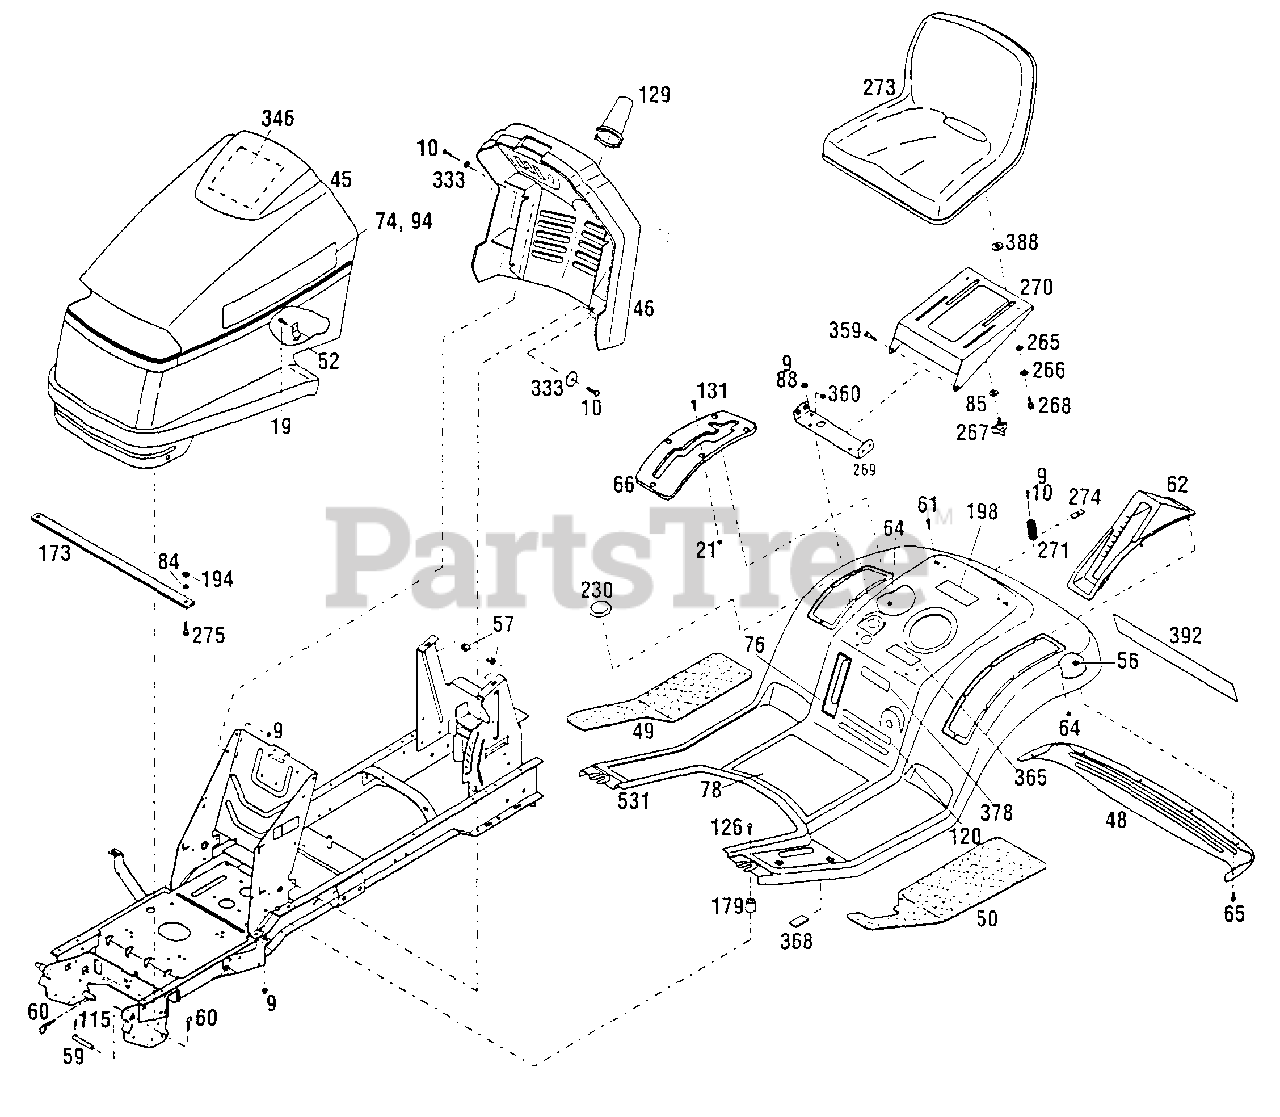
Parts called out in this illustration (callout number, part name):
9	Flange Nut, 5/16-18
10	Hex Head Capscrew, 5/16-18 x 3/4
19	Self Threading Screw, #10
21	Nylon Locknut 1/4-20
46	Console
48	Rear Fender Trim
49	Right Foot Pad 1
50	Left Foot Pad
52	Latch
56	Flange Nut, 1/4-20
57	Self-Retaining Nut, 5/16-18
59	Hood Pivot Pin 1
60	Cotter Spring, 1/8
61	Screw, 5/16-18 x 7/8
62	Lift Handle Cover
64	Self-Threading Nut, 1/4
65	Flange Screw, 1/4-20 x 1/2
66	Quadrant
74	Decal, Logo
76	Decal, Fuel Level
78	Decal, Tunnel
84	Lock Washer, 1/4
85	Flat Washer, 3/8
88	Carriage Bolt, 5/16-18 x 5/8
94	Decal, Logo, Right
115	Drive Pin, 3/16 x 1
120	Decal, Height Indicator
126	Carriage Bolt, 5/16-18 x 3/4
129	Steering Cover
131	Screw, 1/4-20 x 5/8
173	Hood Strap
179	Spacer
194	Nut, 1/4-20
198	Decal, Fuel
265	Nylon Washer, 3/8
266	Bowed Washer, 3/8
267	Adjusting Knob
268	Shoulder Bolt, 3/8-16
269	Seat Bracket
270	Seat Support
271	Compression Spring 2
274	Spring Hold-Down Bracket
275	Screw, 1/4-20 x 5/8
333	Flat Washer 5/16 x 1-1/2
346	Decal, Service
359	Hex Head Cap screw, 3/8-16 x 7/8
360	Locknut, 3/8-16
388	Flat Washer
392	Decal, Model
531	Rear Fender
600	Black Spray Touch-up Paint, 13 oz.
601	Red Spray Touch-up Paint, 13 oz.
